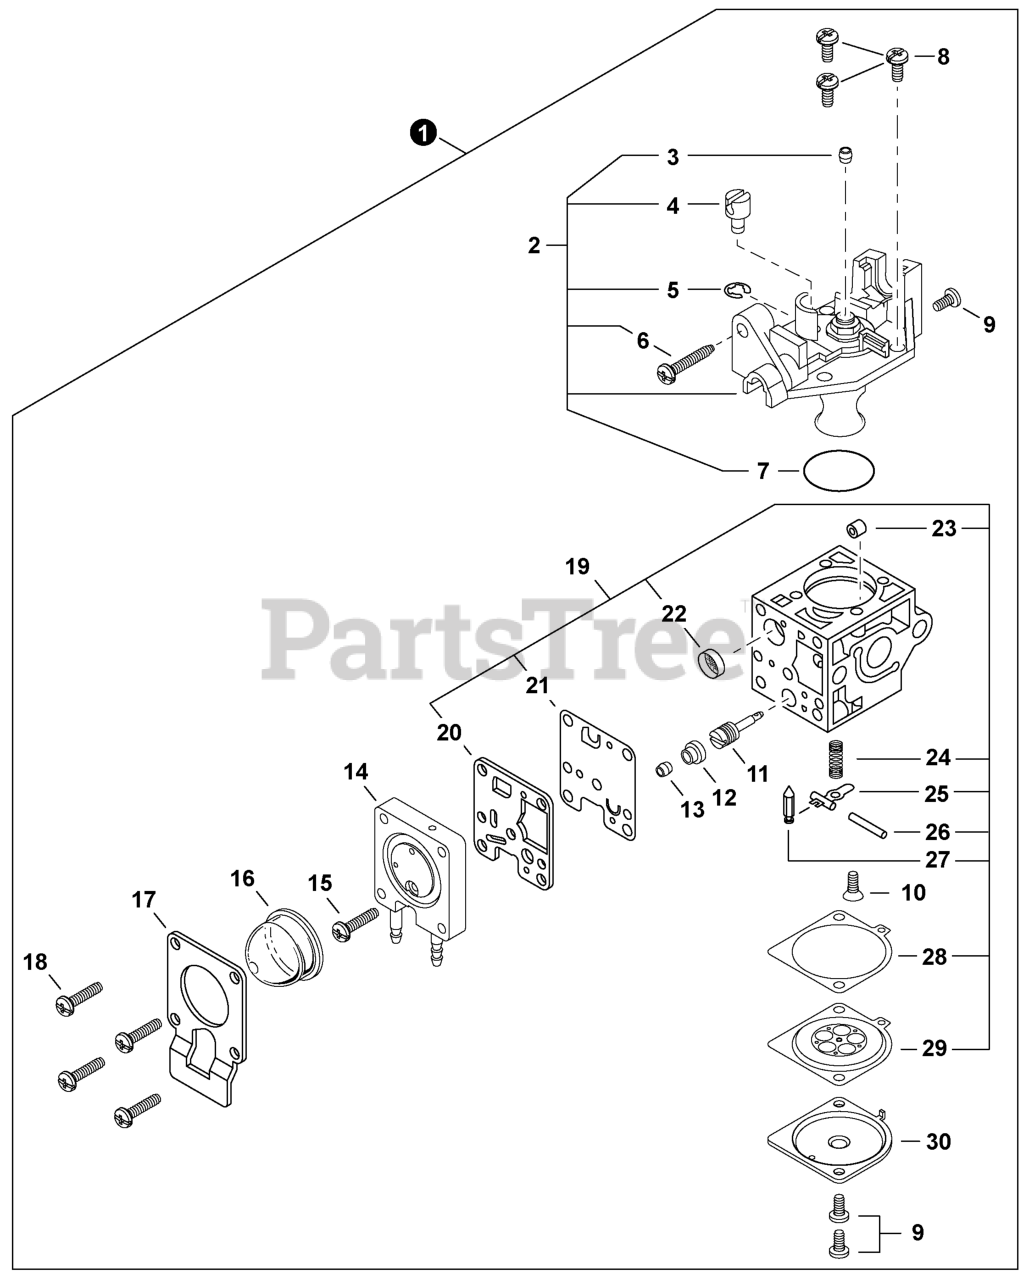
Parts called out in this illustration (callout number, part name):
1	CARBURETOR - Z011-0LA
2	COVER KIT, ROTOR
6	SCREW, IDLE ADJUST
11	NEEDLE, HIGH SPEED
12	CAP, LIMITER
14	BODY ASSY, PURGE
16	BULB, PURGE
17	RETAINER, PURGE BULB
19	REPAIR KIT, CARBURETOR
20	GASKET, PUMP
21	DIAPHRAGM, PUMP
22	SCREEN, FUEL INLET
23	GUIDE, ROLLER
24	SPRING, METERING LEVER
25	LEVER, METERING
26	PIN, METERING LEVER
27	VALVE, INLET NEEDLE
28	GASKET, METERING DIAPHRAGM
29	DIAPHRAGM, METERING
30	COVER, METERING DIAPHRAGM
